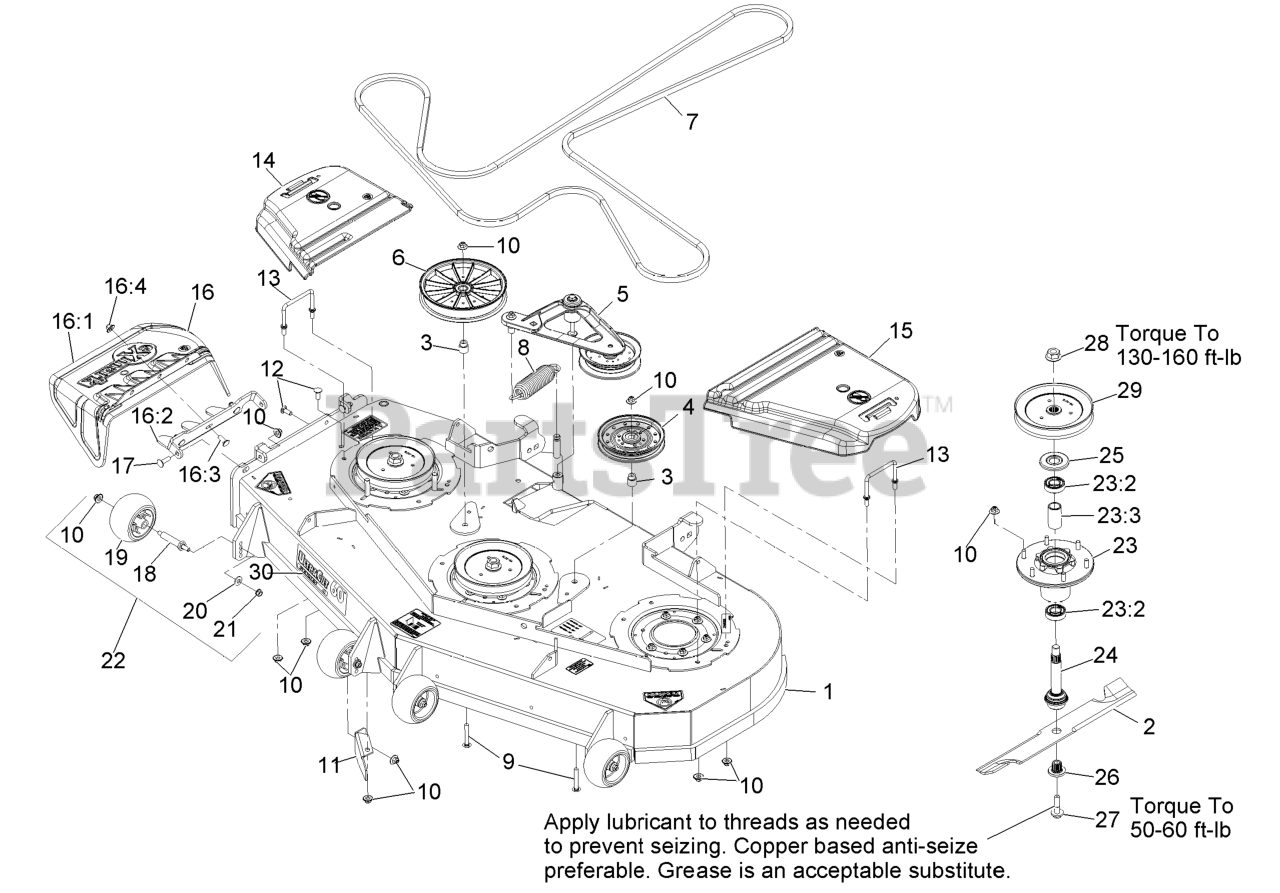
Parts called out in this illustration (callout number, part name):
1	DECK ASM,W/DECALS 60
3	BUSHING-IDLER
5	DECK IDLER ASM
6	PULLEY,IDLER 8"FLAT
7	BELT,V-5V-198.75
9	SCREW-CARR
10	Nut-Nyloc 3/8-16 Flg
11	BAFFLE,DISCHARGE 52/60
12	SCREW-CARR
13	WIREFORM-COVER
14	COVER-BELT, RH
15	COVER-BELT, LH
16	ASM,DISCHARGE CHUTE
16:1	CHUTE,DISCHARGE
16:2	BRACKET,DISCHARGE CHUTE
16:3	SCREW-CARR
16:4	Nut-Nyloc 3/8-16 Flg
17	Bolt-Carriage 3/8-16 X 1 1/4
19	ROLLER-SCALP, ANTI
20	WASHER-BELLEVILLE
21	NUT-HHF, WHIZ
23	ASM-CUTTER HSG WITH BEARINGS
23:2	BEARING-BALL
23:3	SPACER-BEARING
24	ASM-SPINDLE AND SEAL
25	GUARD,BEARING TOP .989
26	BUSHING,SPLINED
27	SCREW,SEMS 1/2-20 X 2.19
28	NUT-FLANGE
29	SHEAVE,BLADE DRIVE 7.25
30	DECAL,ULTRACUT 60 SERIES
